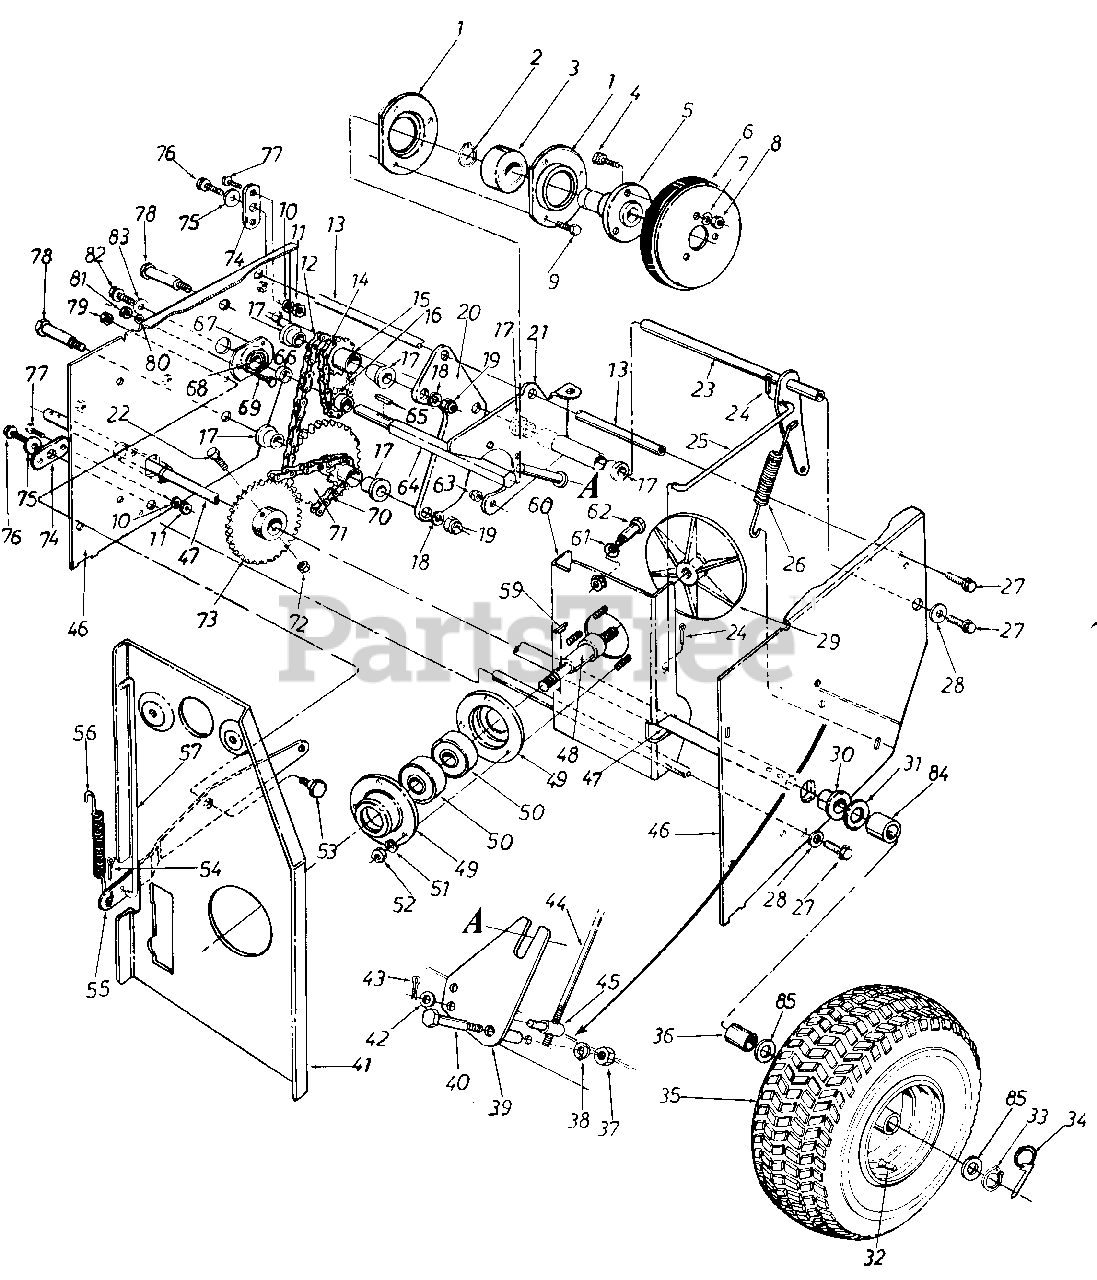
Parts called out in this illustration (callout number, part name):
1	Bearing Housing
2	Snap Ring-1.0" Dia.
3	Ball Brg. .25MM x 52MM x 15MM Thk.
4	Hex Sems Bolt 5/16-18 x .75" Lg.
5	Friction Wheel Adapter
6	Friction Wheel Ass'y.
7	L-Wash. 5/16" I.D.
8	Hex Nut 5/16-18 Thd.
9	Hex Bolt 1/4-28 x .62" Lg.
10	L-Wash. 1/4" I.D.
11	Hex Nut 1/4-20 Thd.
12	#41 Chain-1/2" Pitch x 43 Links
13	Sliding Support Axle
14	#41 Chain-1/2" Pitch x 19 Links
15	9 and 14 Teeth Sprocket Hub Ass'y.
16	8 Teeth Sprocket
17	Flange Bearing .63" I.D.
18	L-Wash. 3/8" I.D.-H.D.
19	Hex L-Jam Nut 3/8-24 Thd.
22	Hex Bolt 1/4-28 x 1.5" Lg.
23	Drive Clutch Brkt. Ass'y.
24	Inter. Cot. Pin 5/16" Dia.
25	Drive Clutch Rod .31" Dia. x 7.38" Lg.
26	Extension Spring 4.31" Lg.
27	Hex L-Bolt 5/16-18 x .62"
28	Fl-Wash. .345" I.D. x .75" O.D.
29	Aluminum Drive Plate
30	Flange Brg. w/Flats
31	Fl-Washer
32	Tubeless Air Valve
33	Snap Ring 3/4" Shaft
34	Klick Pin
35	Wheel Ass'y. Comp. 15 x 6
36	Bearing.75" I.D.
37	Hex Jam Nut 3/8-16 Thd.
38	L-Wash. 3/8" I.D.
41	Engine Brkt. Ass'y.
42	Fl-Wash. .344" I.D. x .62" O.D.
43	Cotter Pin 3/32" Dia. x .75" Lg.
44	Shifting Rod
45	Adjustment Ferrule
46	Frame Ass'y.
47	Free Wheeling Axle
48	Drive Plate Spindle
49	Bearing Housing
50	Ball Brg. .787" I.D. x 1.85" O.D.
51	L-Wash. 5/16" I.D.
52	Hex Nut 5/16-18 Thd.*
53	Shld. Bolt .625" Dia. x .170" Lg.
54	Inter. Cotter Pin 5/16" Dia.
55	Auger Clutch Brkt.
56	Extension Spring .38" O.D. x 3.18" Lg.
57	Auger Clutch Rod .31" Dia. x 10.62" Lg.
59	#61 Hi-Pro Key 3/16" x 518" Dia.
62	Shld. Bolt
63	Hex Ins. Jam Nut 1/4-28 Thd.
64	Hex Shaft
65	#9 Hi-Pro Key 3/32" x 518" Dia.
66	Spacer .51" I.D. x .69" O.D.
67	Bearing Housing
68	Ball Bearing
69	Hex Bolt 1/4-20 x .62" Lg.*
70	#420 Chain .50" Pitch x 29 Links
71	9 and 32 Teeth Sprocket Hub Ass'y.
72	Hex L-Nut 1/4-20 Thd.
73	22 Teeth Sprocket Hub Ass'y.
74	Pivot Axle Brkt.
75	Fl-Wash. .345" I.D. x .75"
76	Hex L-Bolt 5/16-18 x .62"
77	Hex Bolt 1/4-20 x .62" Lg.
78	Sprocket Hub Tubing 1.88"
79	Hex Cent. L-Nut 3/8-16 Thd.
80	L-Wash. 1/4" I.D.
81	Hex Nut 1/4-20 Thd.
82	Hex L-Bolt 5/16-18 x .62"
83	Fl-Wash. .345" I.D. x .75"
84	Spacer.75" I.D.
85	Fl-Washer
